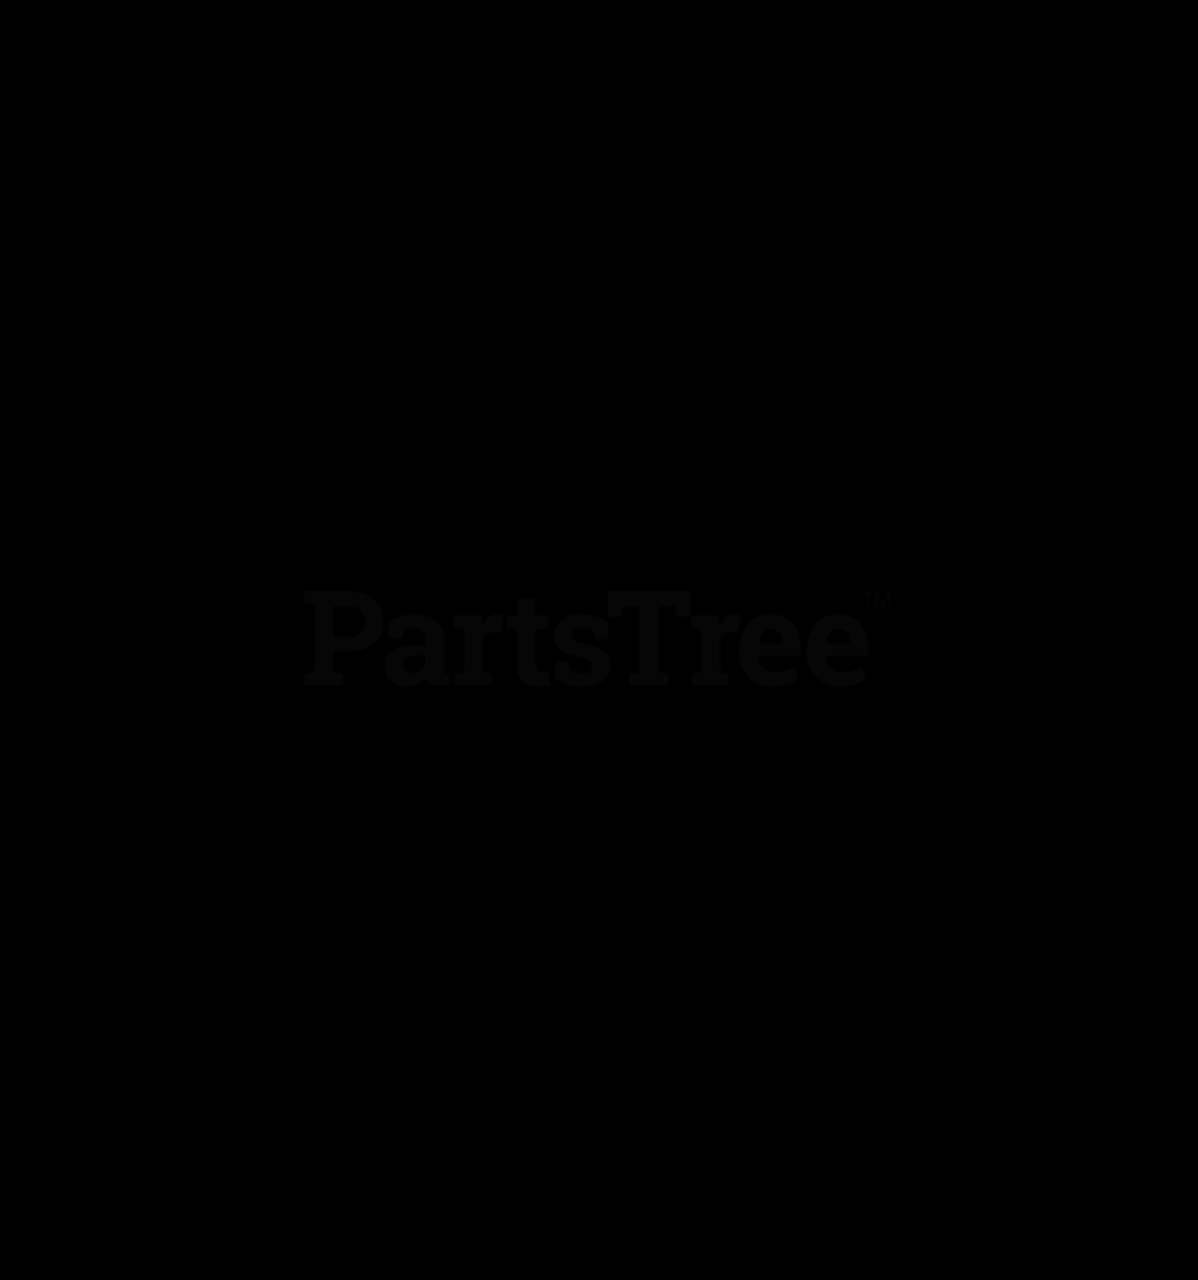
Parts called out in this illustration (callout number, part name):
1	60-in. Discharge Baffle (992215)
2	Nut, .31-18 Nyloc Flange
3	Bolt, Round Head Square Neck .31-18 x 1.00 Grade 5
4	Nut, Heavy Hex .38-16
5	60-in. Right Hand Spindle Guard (992215)
6	60-in. Left Hand Spindle Guard (992215)
7	Nut, Spin Lock Flange .375-16
8	Nut .50-13 Nyloc Flange
9	Anti-Scalp Wheel
11	Bolt, Round Head Square Neck .50-13 x 5.00
12	60-in. Mower Deck (992215)
13	Knob, Clamping .312-18 Nyloc
14	Pin, Pull Plunger .50-13 Thread x .310
15	Nut, Locking Center .31-18
16	Spacer, .510 x .625 x 3.35
17	Chute, Storage Bracket
18	Bolt, Hex .38-16 x 1.00 Grade 5
19	Nut, .38-16 Nyloc Flange
20	Bolt, Round Head Square Neck .50-13 x 8.50
21	Bolt, Round Head Square Neck .31-18 x 1.50
22	Bumper, Recessed 1.50 x .63 , .31 Thru Hole
23	60-inch Discharge Chute Mounting Weldment (992215)
24	Rubber Discharge Chute Support
25	Bolt, Round Head Square Neck .38-16 x 1.00 Grade 5
26	Chute, Rubber Discharge
27	Bolt, Round Head Square Neck .38-16 x 1.25 Grade 5
28	Bolt, Hex .38-16 x 1.25 Grade 5
